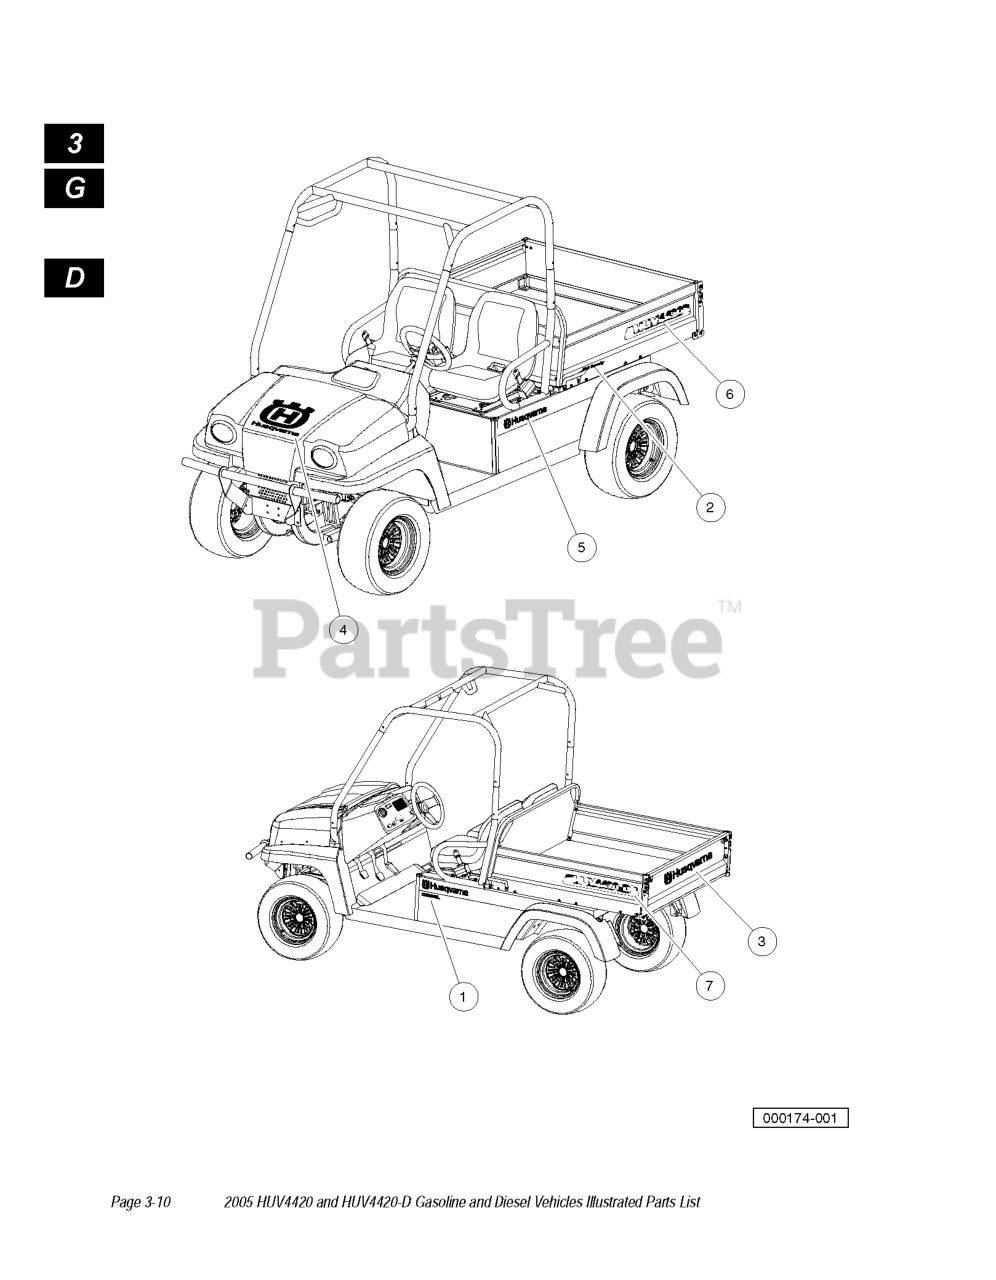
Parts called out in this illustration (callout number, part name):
1	DECAL, DIESEL
2	DECAL, HIGH CAPACITY
3	DECAL, TAILGATE,OEM
4	DECAL HOOD
5	DECAL SIDE PANEL
6	DECAL, BED, HUV4420
7	DECAL, BED, HUV4420-D
